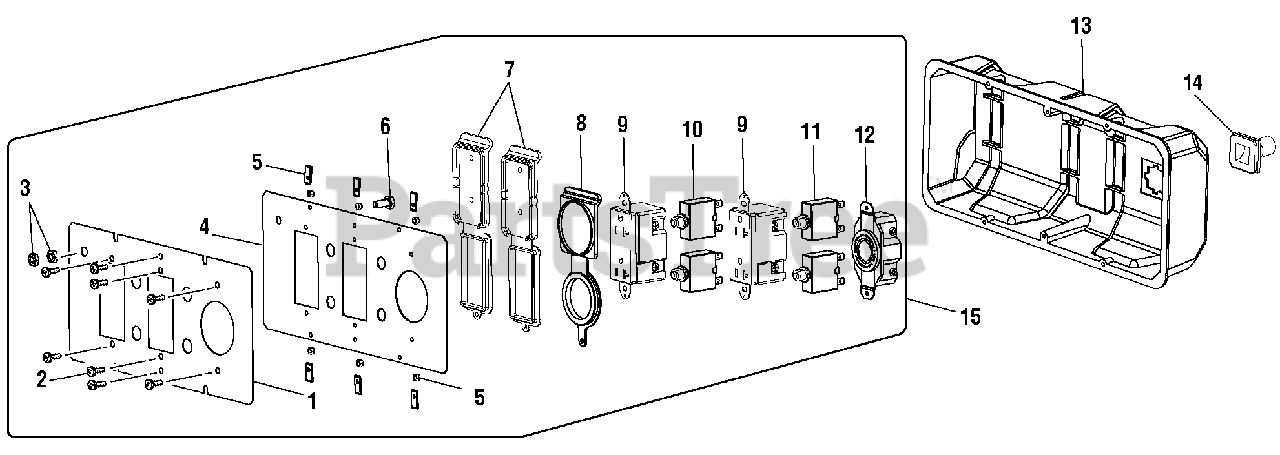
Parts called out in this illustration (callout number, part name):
1	Label (Power Outlet)
2	Screw (6-20 x 3/8 in.)
3	Hex Nut (1/4 in.)
4	Front Panel
6	Bolt (1/4-20 x 16 mm)
7	Receptacle Cover
8	Receptacle Cover
9	120 Volt Duplex Receptacle
10	Circuit Breaker (20 Amp, 125 Volt)
11	Circuit Breaker (30 Amp)
12	Twist Lock Receptacle (120/240 Volt, 30 Amp, L14-30R)
13	Control Box (Back Panel)
14	Rubber Boot
15	Front Panel Assembly
